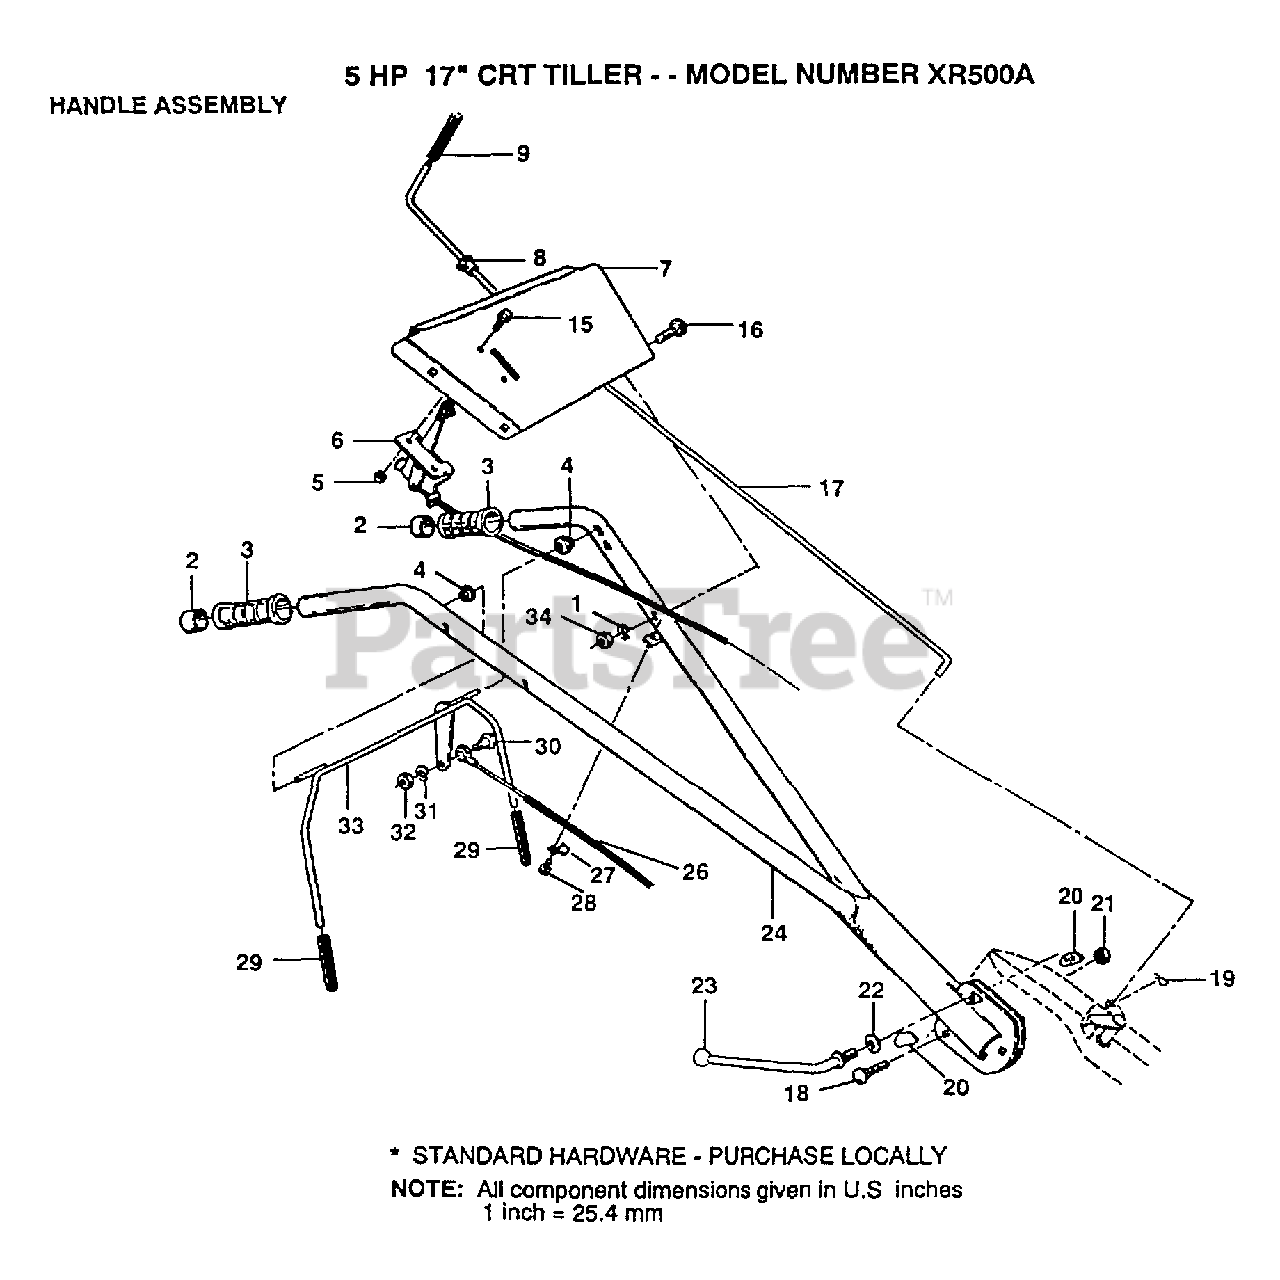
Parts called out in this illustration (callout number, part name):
1	LOCKWASHER
2	CAP CRT
6	"CONT,THROTTLE"
7	"BRKT,HDLE TI"
8	BUSHING
9	GRIP TI
15	SCREW
16	BOLT CARRIAGE CRT
17	ROD SHIFT CRT
18	BOLT D
19	RETAINER M
20	LOCK CRT
26	CABLE.CLUTCH.CRT
27	CONDIUT CLIP T
29	GRIP BAR CRT
30	SHOULDER BOLT ST
31	LOCKWASHER
33	HANDLE BAR CRT
